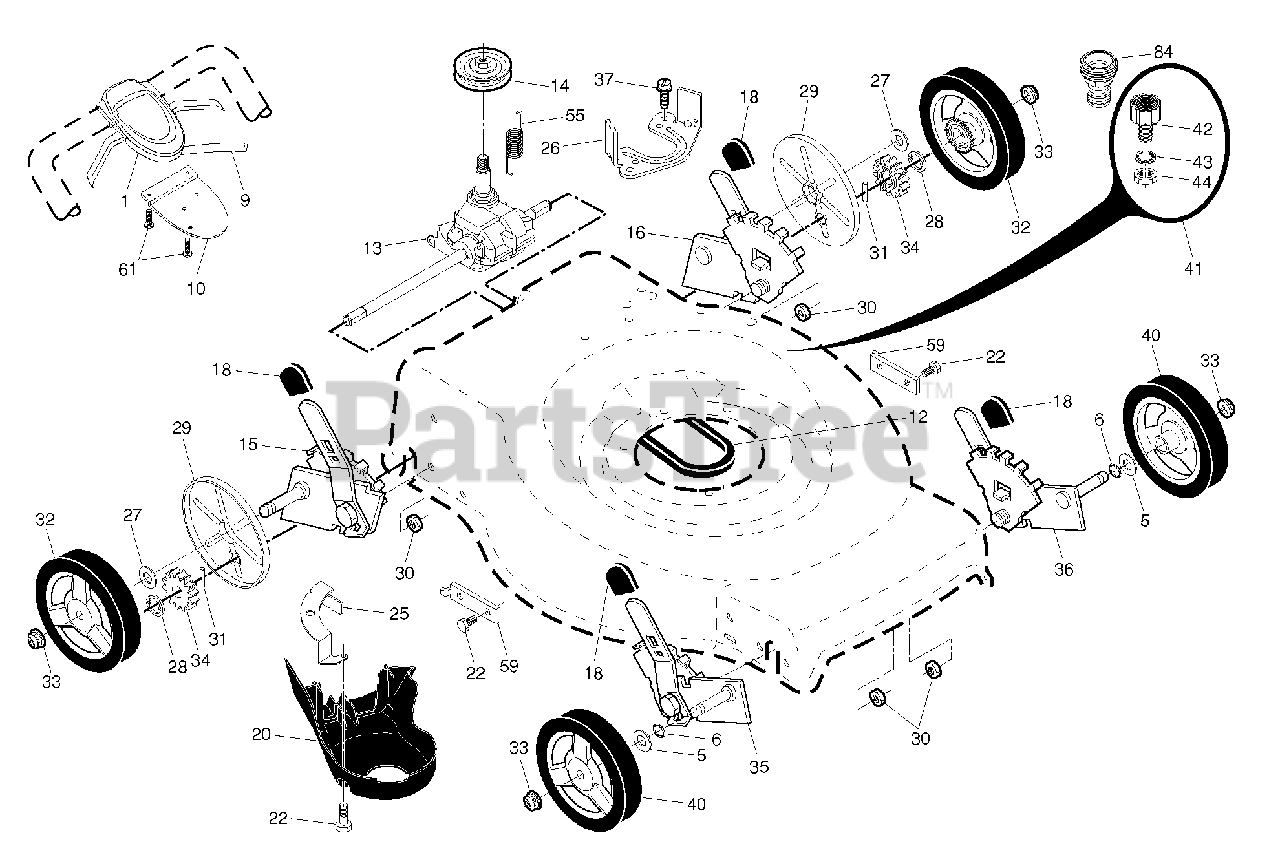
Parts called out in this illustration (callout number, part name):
1	RB CTRL.AW2.22+RGD.BS.GRY/BLK
6	O-RING..070X.487.NEOPRENE
9	CABLE.CONTROL.22RGD.GEN2
10	BRACKET.DRIVE.CONTR.GEN2.BLACK
12	BELT.DRIVE.RGD.PLUS
13	RP TRANSMISSION.22+.RGD.AW2/
15	ADJUSTER.ASM.LH FRONT/RH REAR
16	ADJUSTER.ASM.LH REAR/RH FRONT
18	SELECTOR KNOB
20	COVER.BELT.22.RGD
22	BOLT.5/16HEX.WHS.HD
25	BRACKET.DRIVE.COVER.RGD.BZP
26	BRACKET.TRANS.BELT.KEEPER.BZP
27	WASHER FLUT
28	E-RING 7/16 RE
29	COVER.DUST.WHEEL
30	NUT.HEX.FLANGE.1/4
31	PAWL, DRIVE
32	KIT.WHEEL.442789X460.8"
33	NUT.HEX.FLANGE.3/8-16.LO(3 2)
34	PINIION.14.TOOTH.RGD
35	ADJUSTER.ASM.9POS.LW.RGD.FR
36	ADJUSTER.ASM.LH FRONT/RH REAR
40	WHEEL.8IN.H3SPK.ALPHA.
41	KIT.WASH-OUT.PORT.ZINC.WALK
42	WASHOUT.PORT.ZINC.RGD.22+
43	WASHER.LOCK.INTERNAL.TOOTH
44	LOCKNUT.HEX.WITH.O-RING
59	BRACKET.SUPPORT.22+RWGD.BZP
61	SCREW, PHILLIPS HEAD 10 X 5/8
84	COUPLING.QUICK CONNECT
